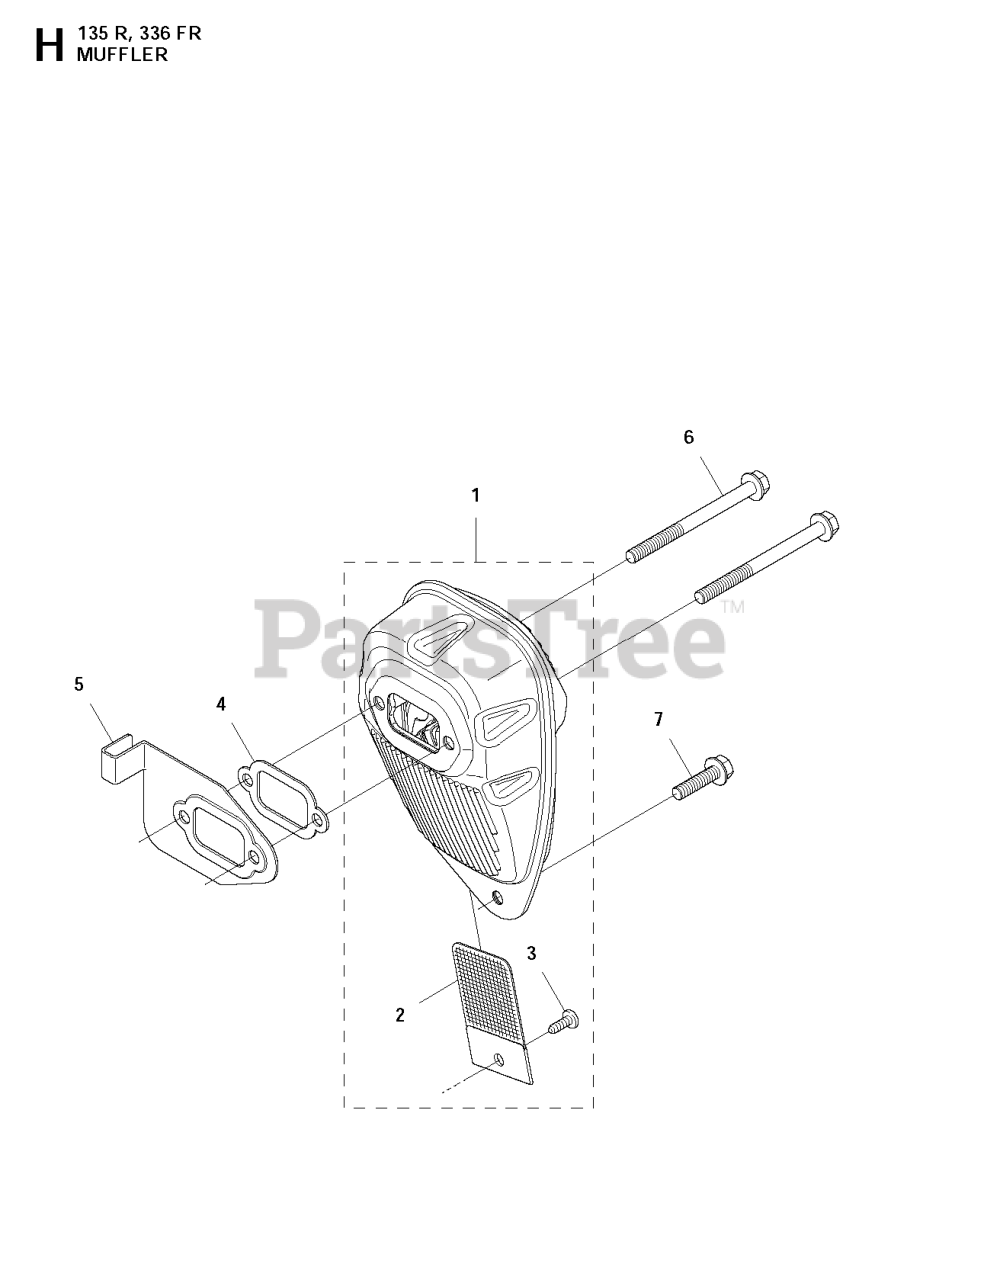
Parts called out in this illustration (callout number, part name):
1	MUFFLER
2	SPARK ARRESTER SCREEN
4	GASKET MUFFLER
